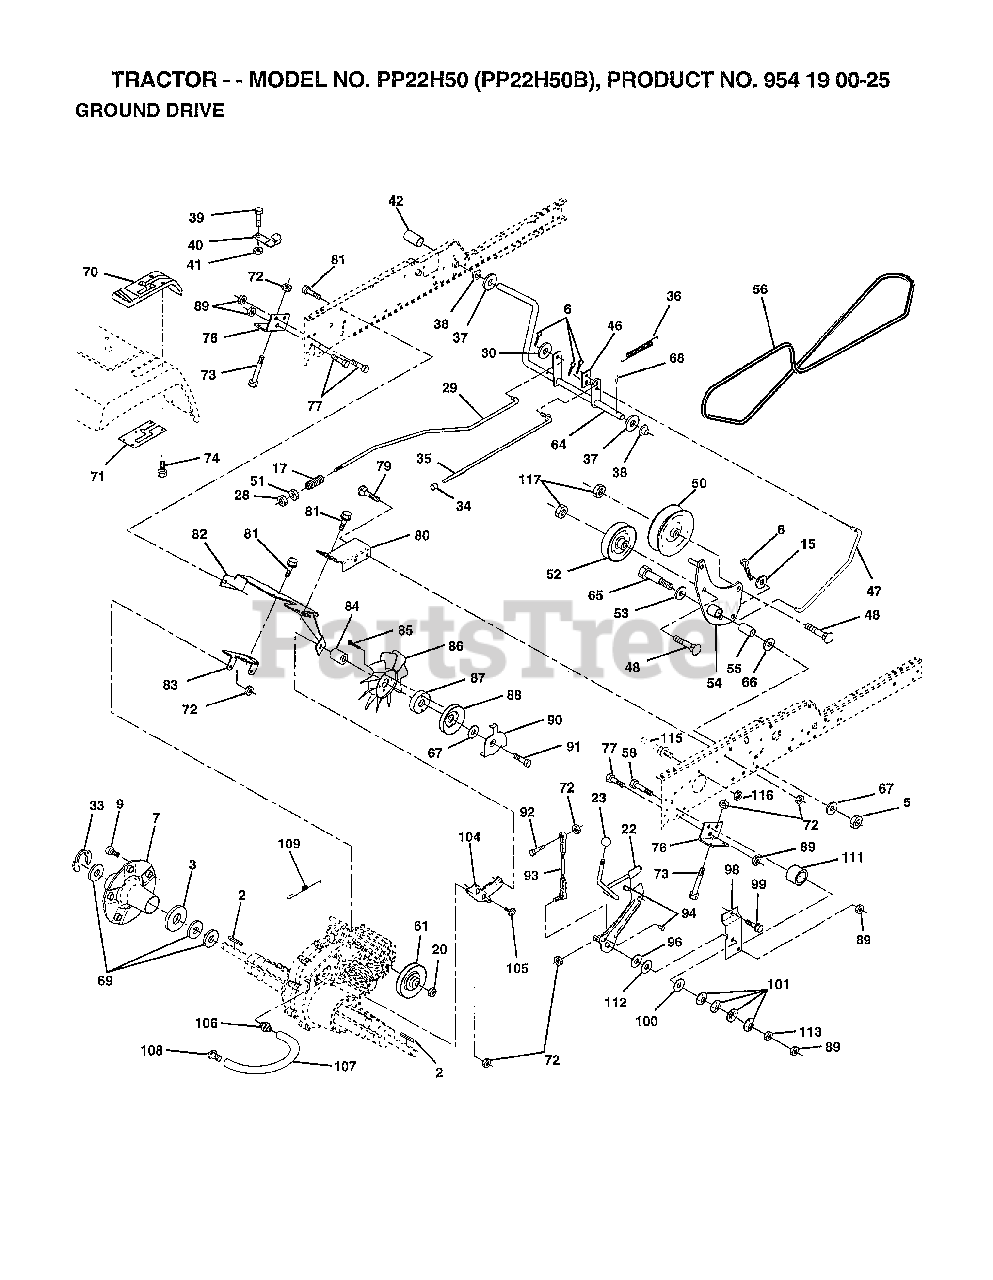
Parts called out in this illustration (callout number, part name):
2	KEY 1/4 X 2.5
3	WASHER T
5	NUT
6	COTTER PIN
7	HUB WHEEL ASM
9	BOLT.HUB.WHL.REAR
15	WASHER
17	SPRING ROD BRAKE
22	ARM ASM SHIFT
23	KNOB.DUCKHEAD.1/2
28	NUT
29	ROD BRAKE
30	WASHER HYT
33	E RING HYT
34	PLUNGER CAP T
35	ROD BRAKE PART GT
36	SPRING.GRND.DRIVE
37	WASHER
38	BUSHING.NYLINER
39	SCREW
40	ACT-SWITCH T
42	"COVER,PEDAL"
46	RETAINER.SPRING
47	ROD.CLUTCH
48	BOLT.3/8-16X1.50
50	FLAT IDLER PULLEY
52	PULLEY.IDLER.V.GR
53	WASHER T
54	CLUTCH.ARM.ASM
55	"LY, BEARING"
56	BELT-V 84.5
58	BOLT
61	PULLEY TRANSAXLE
64	SHAFT-BRAKE/CLUTC
65	AXLE BOLT
66	WASHER.HARD.BLADE
67	WASHER
68	ROLL PIN STD
69	WASHER
71	"PLATE CONSOLE,SFT"
72	NUT
73	BOLT.HEX.FLGHD.
74	SCREW HEXWSH H-L
76	BRACKET TRAN VGTH
77	BOLT
79	BOLT
80	BRACKET TORQUE RH
81	SCREW
82	BRACKET.MTG.FAN
83	STRAP TORQUE MID
84	SPACER
85	SCREW YTV
86	"FAN 7"" HYDRO"
87	ADAPTER FAN
88	PULLEY FAN
89	NUT GTV
90	KEEPER BELT
91	SCREW.HXWSH.3/8
93	LINK ASM SHIFT
94	XMAS TREE FASTNER
96	WASHER NICKEL PLT
98	BRACKET SHIFT
99	SCREW LT
100	WASHER COMPRESSIN
101	WASHER-BELLVILLE
104	BRACKET IDLER
105	SCREW CRT
106	O-RING.ASM.70110
107	"LINE FUEL,HYD 15"""
108	CAP.VENT.70109
109	SPRING BRAKE
111	"SPACER-LEVER,SHIF"
112	"WASHER-NYLON,HIGH"
113	NUT
115	"KEEPER,DRIVE BELT"
116	"NUT HEX,LOCK,FLAN"
